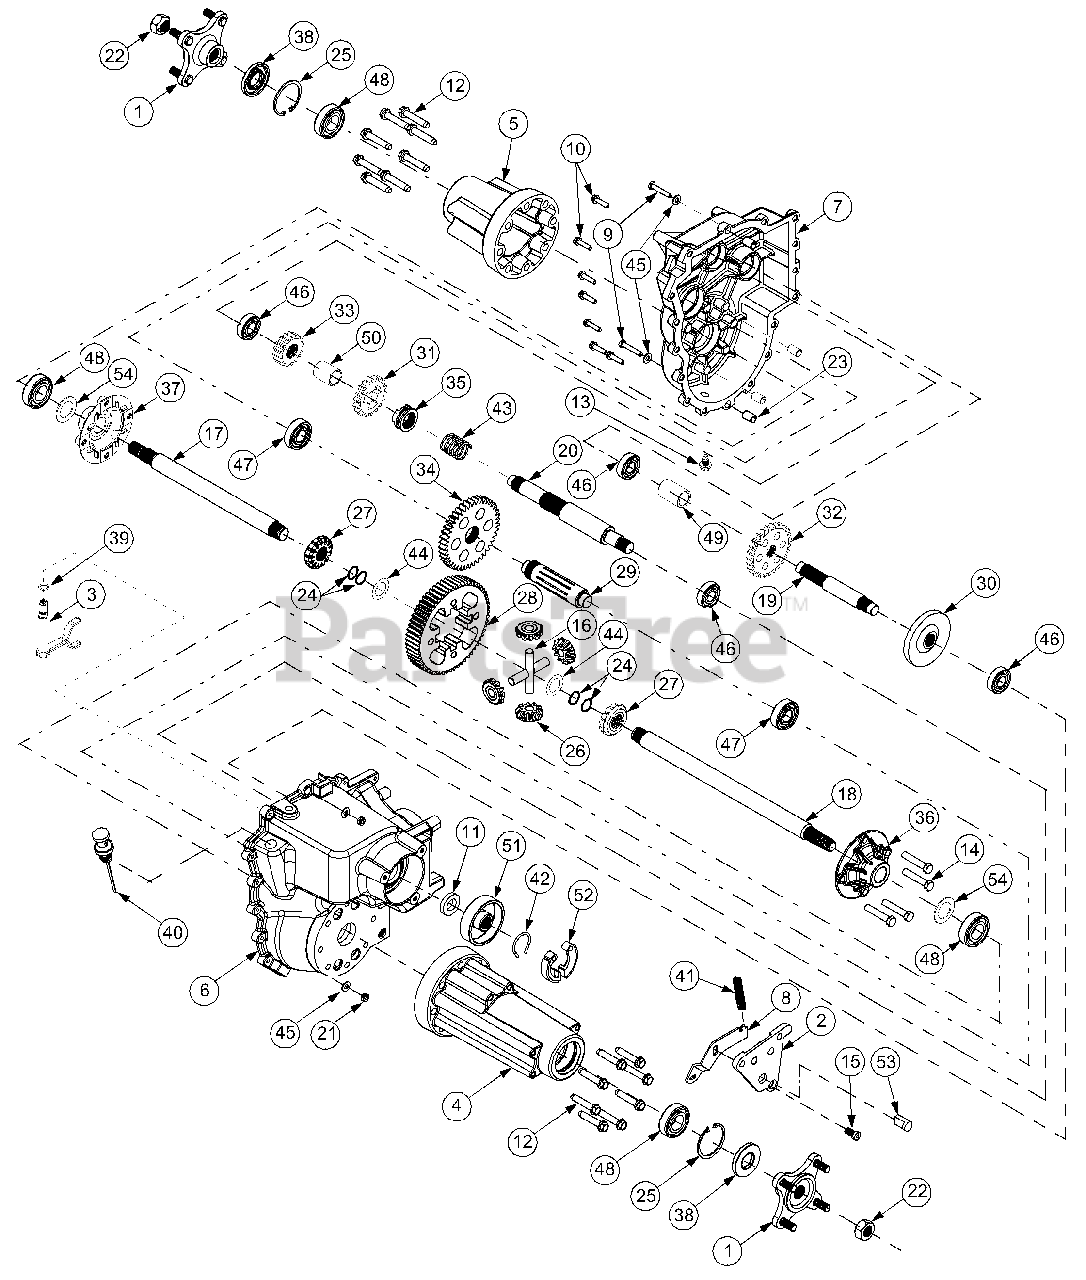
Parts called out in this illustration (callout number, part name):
1	Hub Assembly, Wheel
2	Plate Assembly, Brake
3	Shift Yoke Assembly
4	Axle Housing, RH
5	Axle Housing, LH
6	Transmission Housing, RH
7	Transmission Housing, LH
8	Brake Arm
9	Screw, Hex Cap, 1/4-20 x 1.5
10	Screw, Hex Wash Hd Tap, 1/4-20 x 1.0
11	Seal, Shift Shaft
12	Screw, TT, 3/8-16 x 1.875
13	Screw, Plug, M14 x 1.5 x .827
14	Screw, Hex Hd Cap, 3/8-24 x 2.0 GR5
15	Screw, Cap, 3/8-16 x .750
16	Shaft, Cross, .500 x 3.005
17	Shaft, Axle, 1.00 x 12.90
18	Shaft, Axle, 1.00 x 16.62
19	Shaft, Drive
20	Shaft, Shifter
21	Nut, Hex Center Lock, 1/4-20
22	Nut, Hex, 3/4-16
23	Dowel Bushing
24	Ring, Retaining, .750
25	Ring, Retaining,
26	Gear, Miter, 10T
27	Gear, Miter, 14T
28	Gear, Differential Spur, 60T
29	Shaft, Output, 9T
30	Gear, Bevel, 36T
31	Gear, Spur, 18T
32	Gear, Spur, 27T
33	Gear, Spur, 16T
34	Gear, Spur, 42T
35	Collar, Drive
36	Housing, Differential, RH
37	Housing, Differential, LH
38	Seal, Oil, 25.4mm x 54mm x 7mm
39	O-Ring, 3/8 ID x 1/2 OD x 1/16 Thk
40	Dipsick, Oil
41	Spring, Compression
42	Spring, Brake Shoe
43	Spring, Compression, 1.015 ID x 1.6
44	Washer, Flat, 1.0 x 1.56 x .010 Thk
45	Washer, Flat, .25 x .630 x .0515
46	Bearing, Ball, 17 ID x 40 OD x 12
47	Bearing, Ball, 6204
48	Bearing, Ball, 6205-1
49	Spacer, .757 x 1.0 x 1.460
50	Spacer, .885 x 1.125 x 1.40
51	Drum, Brake
52	Brake, Shoe
53	Brake, Actuator
54	Washer, Flat, 1.010 x .56 x .060
